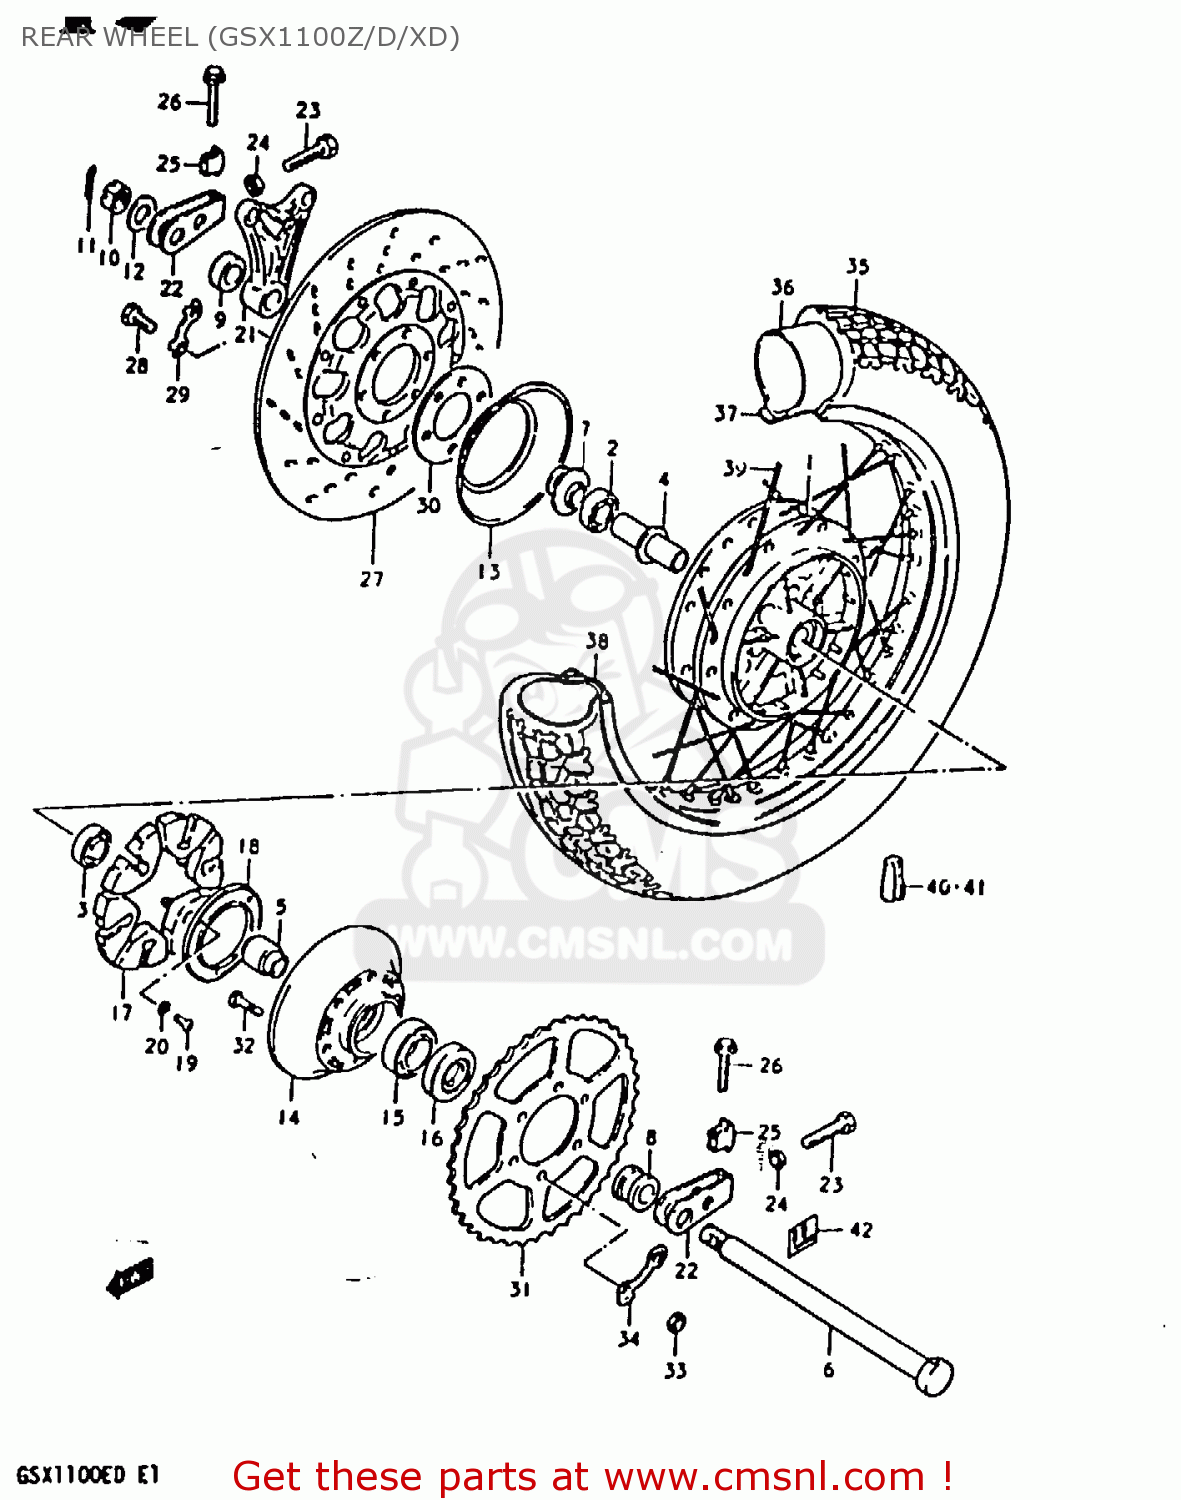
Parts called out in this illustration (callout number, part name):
1	DRUM,REAR HUB
2	BEARING
3	BEARING, LH
4	SPACER,REAR HUB BEARING
5	SPACER,REAR HUB BEARING
6	AXLE,REAR
7	SPACER,REAR AXLE,RIGHT
8	SPACER(20X33X28.3)
9	SPACER(20X38X12)
10	NUT 18MM
11	PIN,COTTER
12	WASHER(19X34X4)
13	COVER,REAR WHEEL HUB
14	DRUM,REAR SPROCKET MOUNT
15	BEARING
16	SEAL,OIL(33X62X7)
17	ABSORBER,REAR HUB SHOCK
18	PLATE,REAR HUB SHOCK ABSORBER
19	SCREW
20	LOCK WASHER
21	BRACKET,RR,CALIPER
22	ADJUSTER,CHAIN
23	BOLT
24	NUT
25	SUPPORTER,CHAIN ADJUST
26	BOLT (8X40)
27	DISC,RR BRAKE
28	BOLT 8X40
29	WASHER
30	SHIM,BRAKE DISC
31	SPROCKET,REAR
32	BOLT
33	NUT
34	WASHER
35	TIRE
36	TUBE ASSEMBLY,WHEEL,INNER
37	PROTECTOR,INNER TUBE
38	RIM (MT2.50*17)
39	SPOKE SET
40	BALANCER,WHEEL (B)
41	BALANCER,WHEEL (30G)
42	LABEL,CHAIN WEAR INDICATOR
